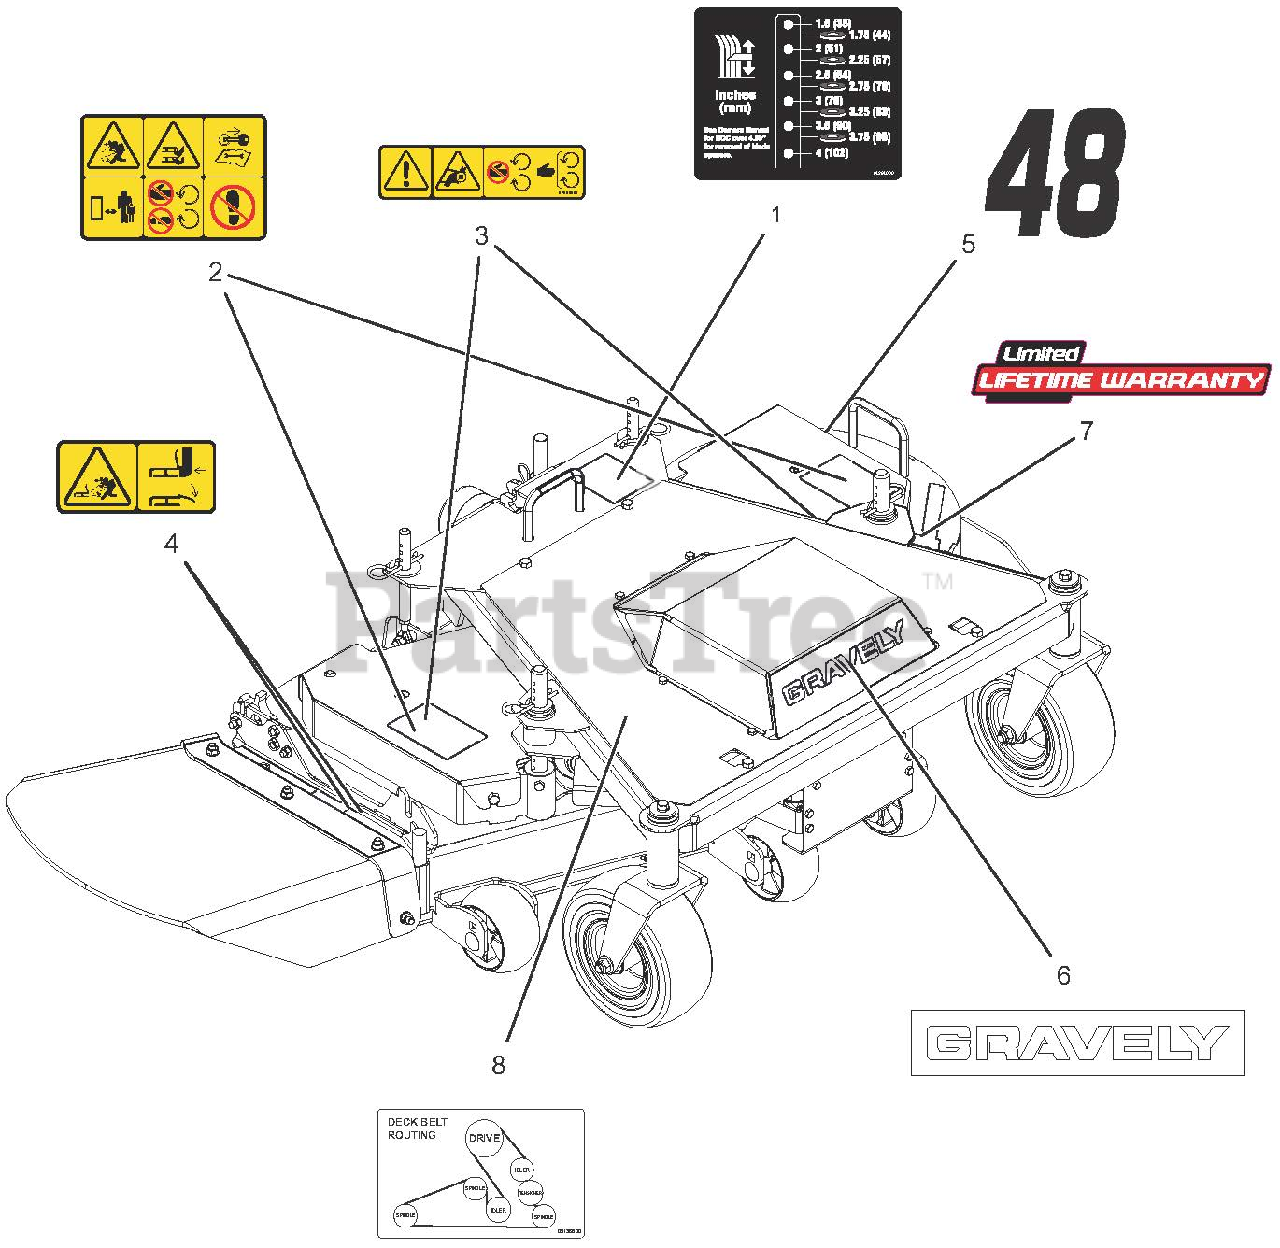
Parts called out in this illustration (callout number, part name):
1	DECAL, PROWALK HEIGHT OF CUT
2	DECAL, SAFETY - MOWER DECK
3	DECAL, SHIELD REMOVED
4	DECAL, SAFETY - DECK GUARDING
5	DECAL, 48"
6	DECAL, 9.5" GRAVELY LOGO
7	DECAL, LIMITED LIFETIME WARR
8	DECAL, BELT ROUTING 48"
